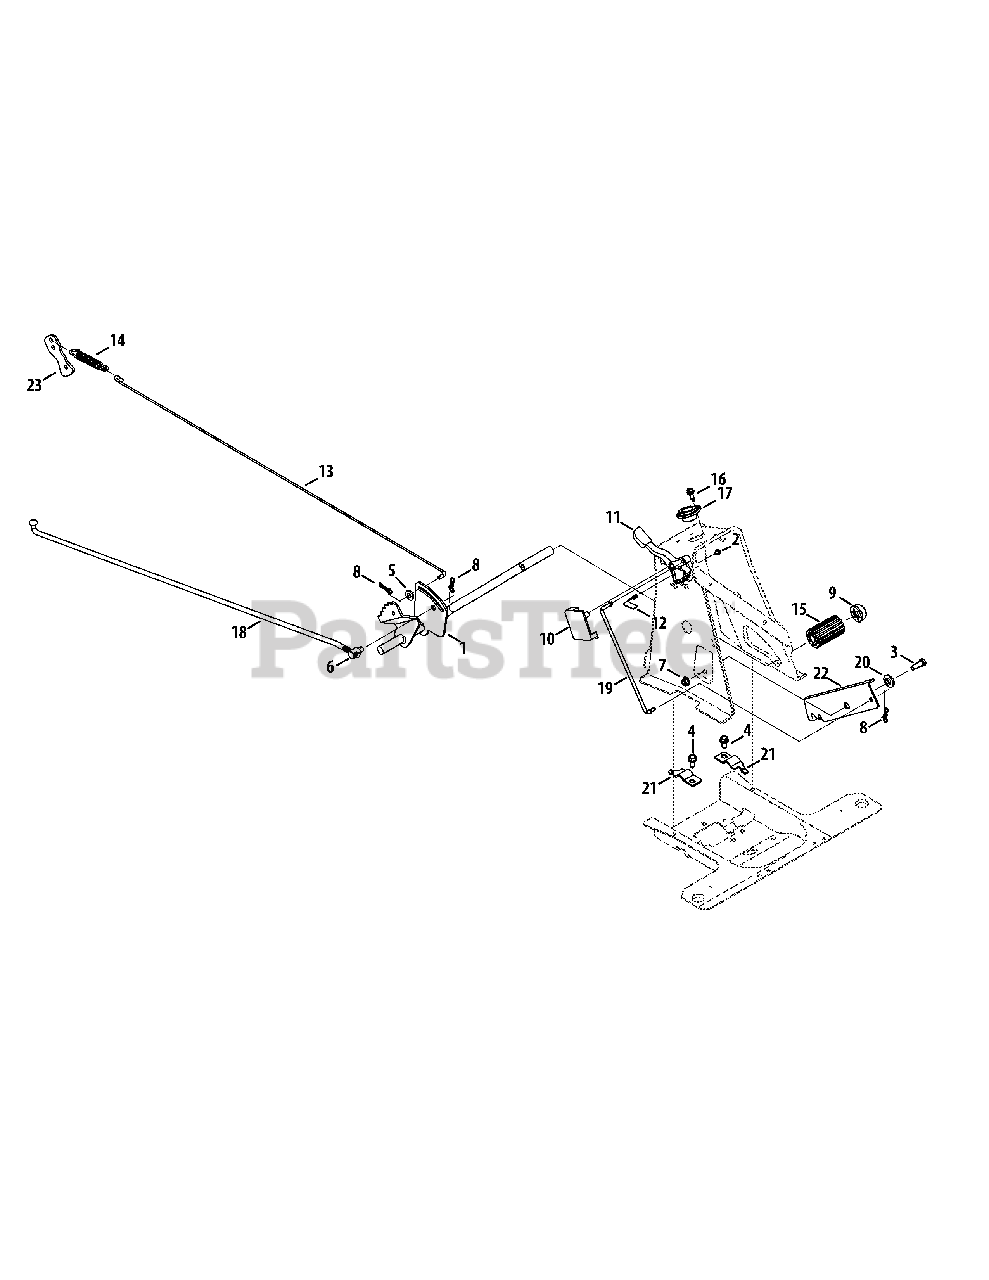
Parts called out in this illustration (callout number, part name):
1	Brake Pedal Assembly
2	Screw #10-16 x 0.500
3	Hex Head Screw 5/16-18 x 1.00
4	Tap Screw 5/16-18 x .750
5	Flat Washer .330 x .630 x .064
6	Ferrule 3/8-24 x .375 Dia.
7	Flange Lock Nut 5/16-18
8	Bow-Tie Cotter Pin
9	Push Cap, 5/8
10	Speed Control Cover
11	Speed Lever, 6-SPEED
12	Shift Spring
13	Brake Rod
14	Extension Spring .59 OD x 4.00 Lg.
15	Foot Pad
16	Shoulder Screw .368 x .113, 1/4-20
17	Steering Col. Bearing .880 ID x 1.36
18	Variable Speed Control Rod
19	Speed Selector Control Rod
20	Shoulder Spacer
21	Pedal Strap Support Bracket, 5/8
22	Speed Latch Bracket
23	Brake lever Bracket
